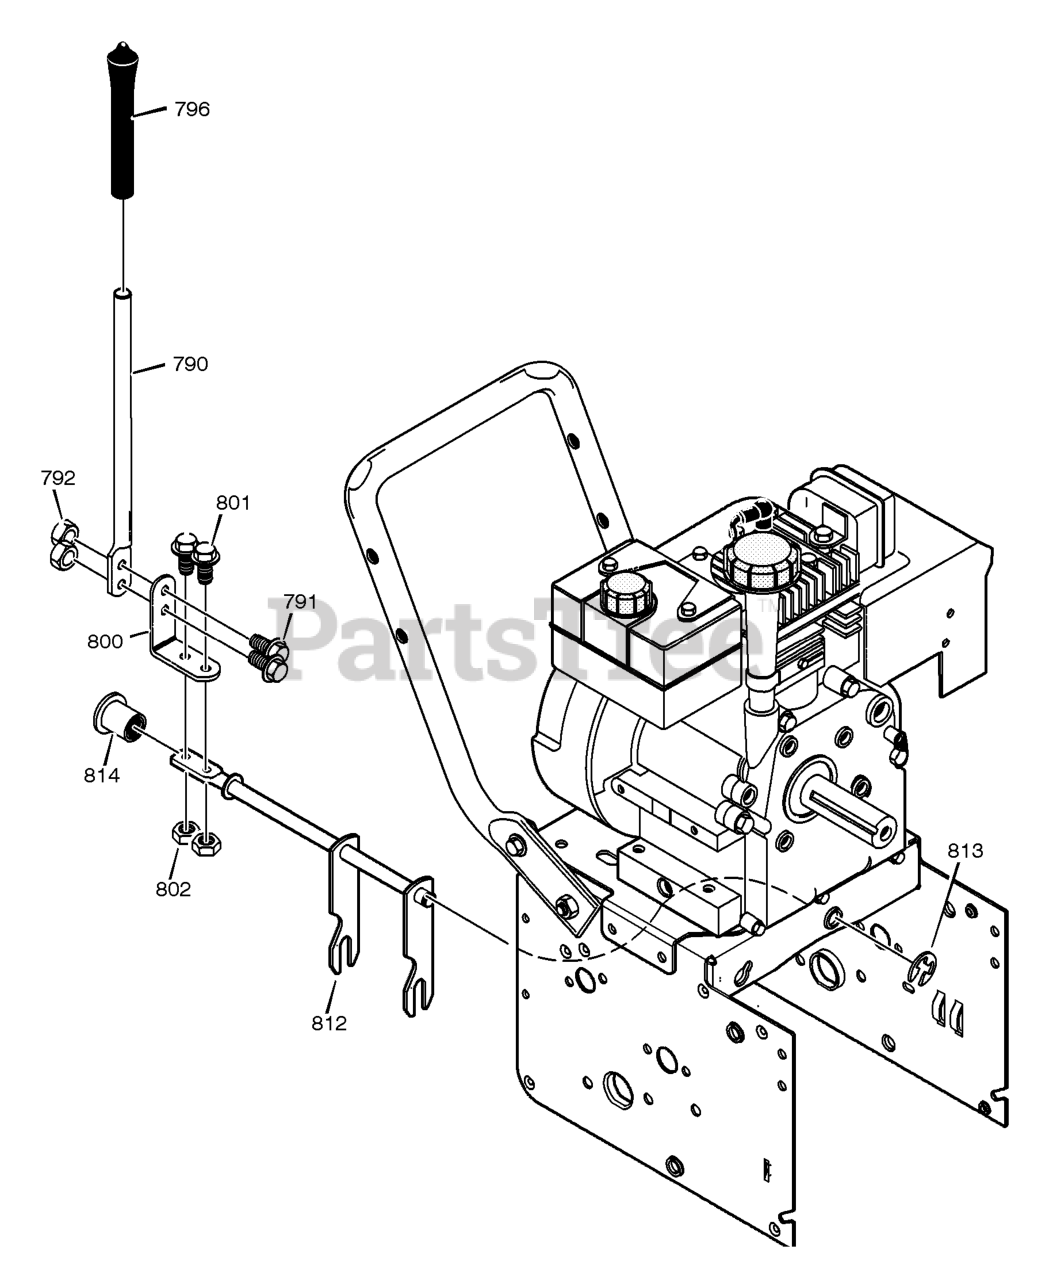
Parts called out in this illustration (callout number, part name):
790	ROD, SHIFT
791	SCREW, 1/4-20X.75
792	NUT, 1/4-20
796	KNOB, SLIP
800	LEVER, SPRING
801	SCREW, 1/4-20X.75
802	NUT, 1/4-20
811	BEARING, FLANGED
812	ROD ASSY., SPEED SELECT
813	RETAINER, RING
